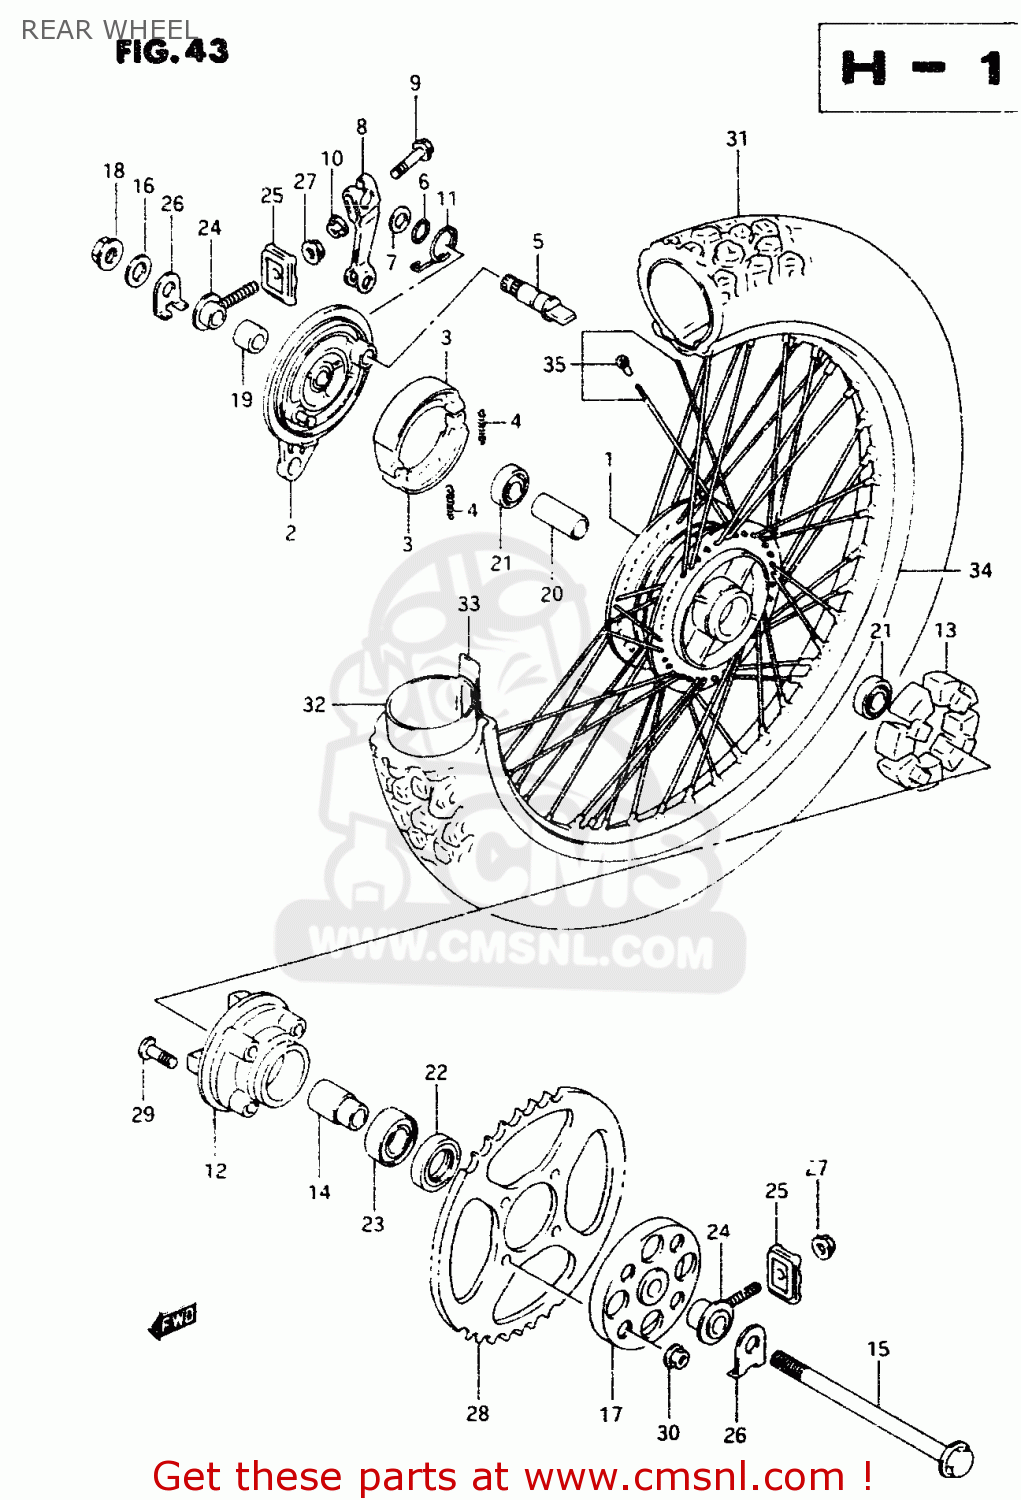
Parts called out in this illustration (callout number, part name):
1	HUB,RR WHEEL
2	PANEL,RR HUB
3	SHOE,RR BRAKE
4	SPRING(L:35.8)
5	CAM,RR BRAKE
6	O-RING (D:2.4 ID:13.8)
7	WASHER (14.5X22X1.6)
8	LEVER,RR BRAKE CAM
9	BOLT
10	NUT
11	SPRING
12	DRUM,RR SPROCKET
13	ABSORBER,SHOCK
14	RETAINER,RR SPROCKET DRUM
15	AXLE,REAR
16	WASHER
17	SPACER
18	U NUT
19	SPACER(12.1X22X20)
20	SPACER(12.1X17.3X62)
21	BEARING
22	SEAL OIL(25X40X6)
23	BEARING(17X40X12)
24	ADJUSTER,CHAIN
25	PLATE,CHAIN ADJUSTER GUIDE
26	WASHER,CHAIN ADJUSTER
27	NUT
28	SPROCKET RR
29	BOLT
30	NUT
31	TIRE 3.00-18 077-458MM
32	TUBE,INNER
33	PROTECTOR,WHEEL,INNER
34	RIM,FR WHEEL
35	SPOKE SET,RR WHEEL
